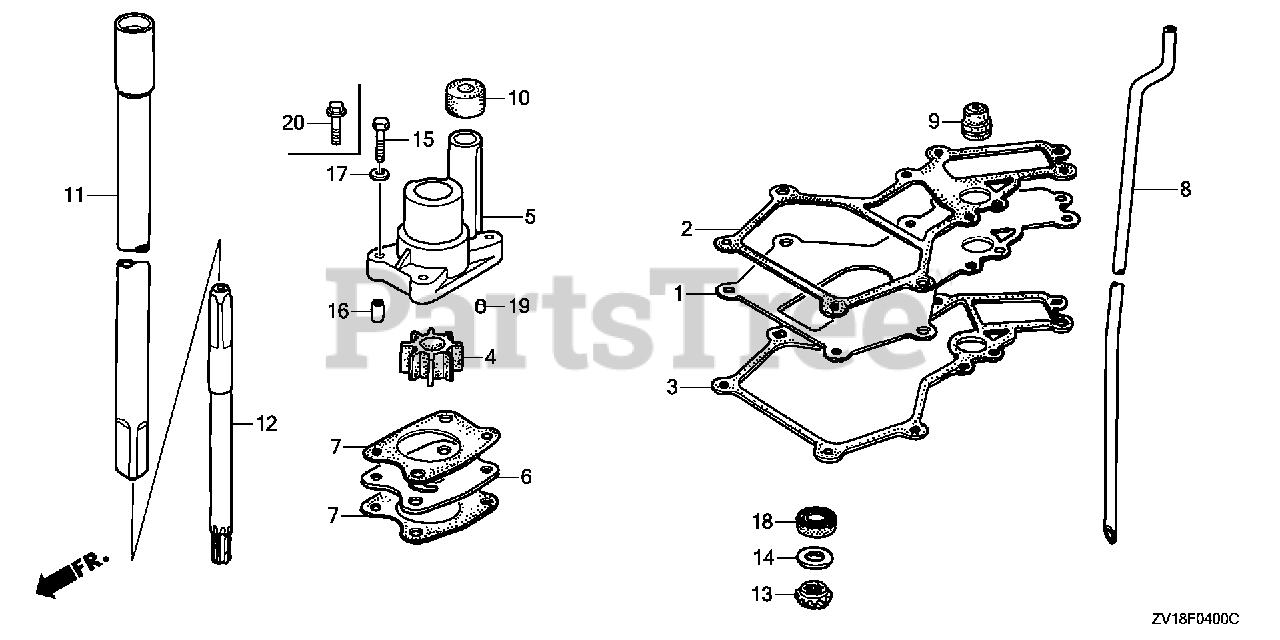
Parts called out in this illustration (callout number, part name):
1	PLATE, EX. CHAMBER
2	GASKET, EX. CHAMBER (UPPER)
3	GASKET, EX. CHAMBER (LOWER)
4	IMPELLER, PUMP
5	HOUSING, IMPELLER
6	COVER, IMPELLER
7	GASKET, IMPELLER
8	TUBE, WATER (L)
9	GROMMET, WATER TUBE
10	RING, WATER TUBE SEAL
11	SHAFT, VERTICAL (L)
12	SHAFT, PINION
14	WASHER A (1.00MM)
14	WASHER B (1.05MM)
15	BOLT, HEX. (6X28)
16	COLLAR B, DISTANCE
17	WASHER, PLAIN (6MM) Use from Frame SN 4800713.
18	SEAL, WATER (13MM) (ARAI)
19	ROLLER (4X10)
20	BOLT-WASHER (6X29)
